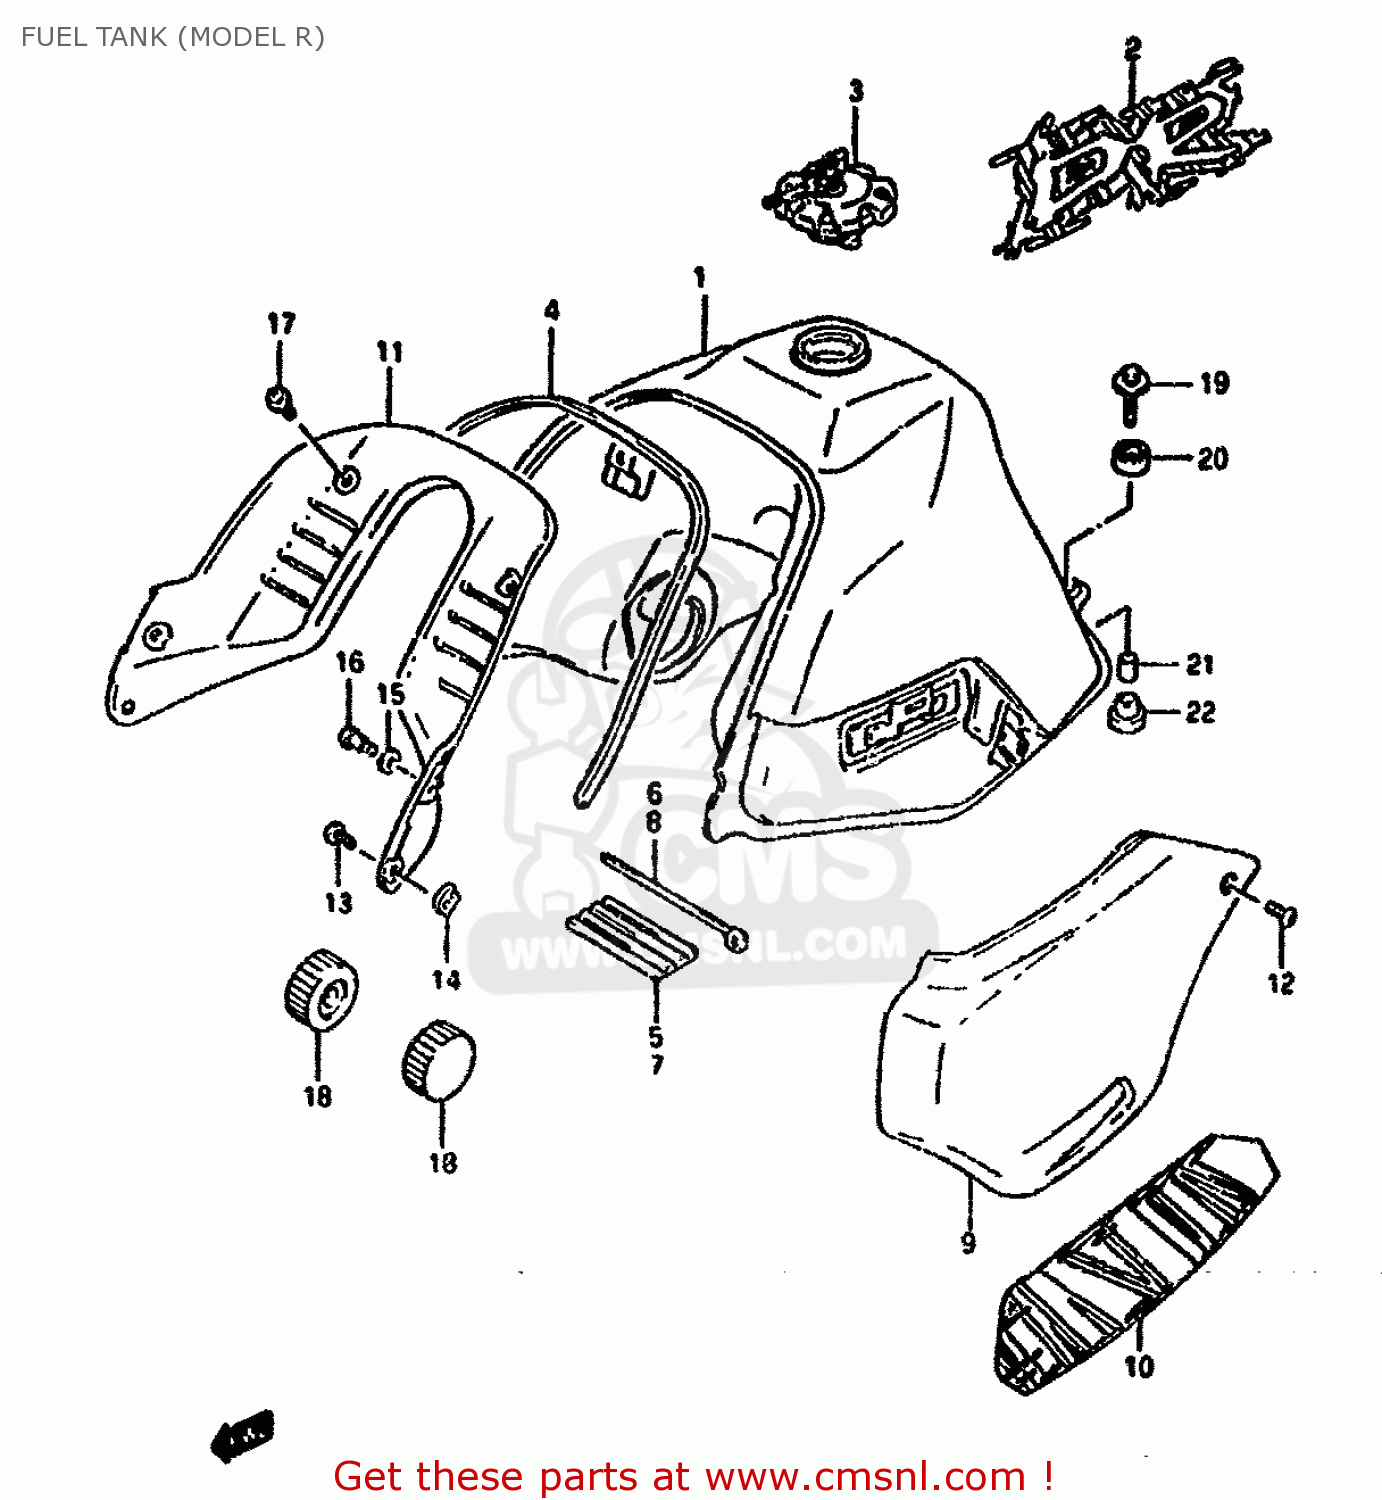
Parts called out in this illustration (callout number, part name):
1	TANK ASSY, FUEL (BLACK)
2	TAPE SET, FUEL TANK
3	CAP SET,FUEL TANK
4	MOLDING,FUEL TANK
5	CUSHION,FUEL TANK UPR FR
6	CLAMP
7	CUSHION,TANK UPR RR
8	CLAMP(L:300)
9	COVER,FUEL TANK,R
10	TAPE,TANK COVER,R
11	COVER,FUEL TANK,FRONT
12	SCREW
13	SCREW
14	NUT
15	WASHER (5.1X20X1.4)
16	SCREW(5X18)
17	SCREW
18	CUSHION,FUEL TANK FR
19	BOLT
20	CUSHION
21	SPACER
22	CUSHION
